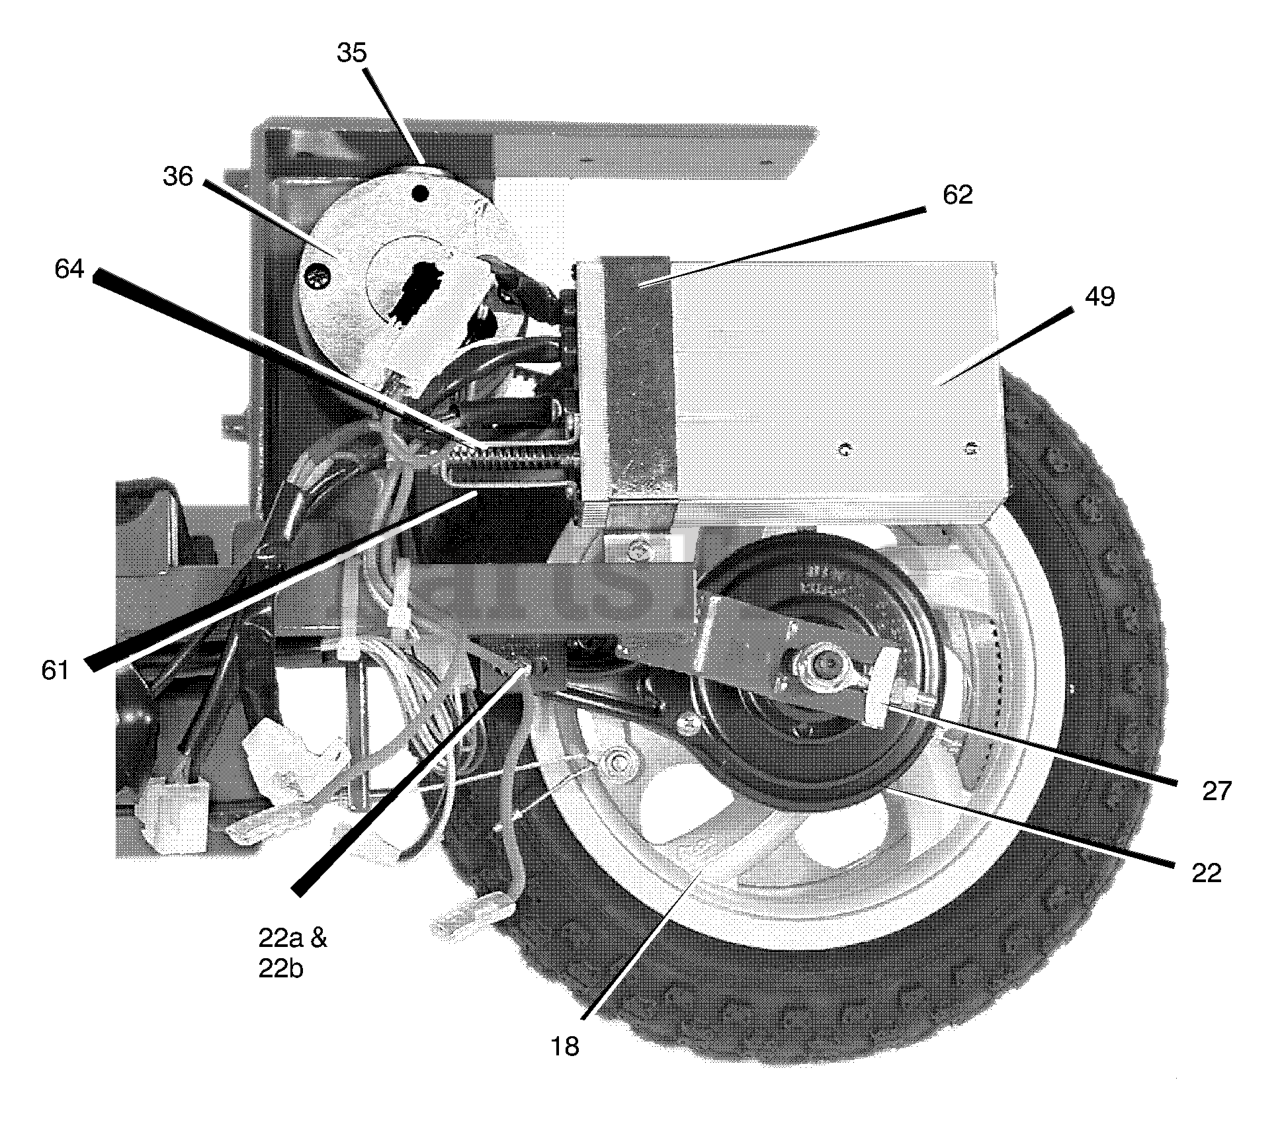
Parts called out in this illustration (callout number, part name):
18	Wheel Assembly, Rear
22	Brake Assembly
22A	Screw, Brake Assembly Mounting (1 required)
22B	Nut, Brake Assembly Mounting (1 required)
27	Adjuster Ass'y., Rear Wheel
35	Brush, Motor (2 required)
36	Motor, Drive (DC)
49	Controller, Microcomputer
61	Bracket, Throttle Cable Mount
62	Bracket, Controller Mount
64	Spring, Throttle Control
